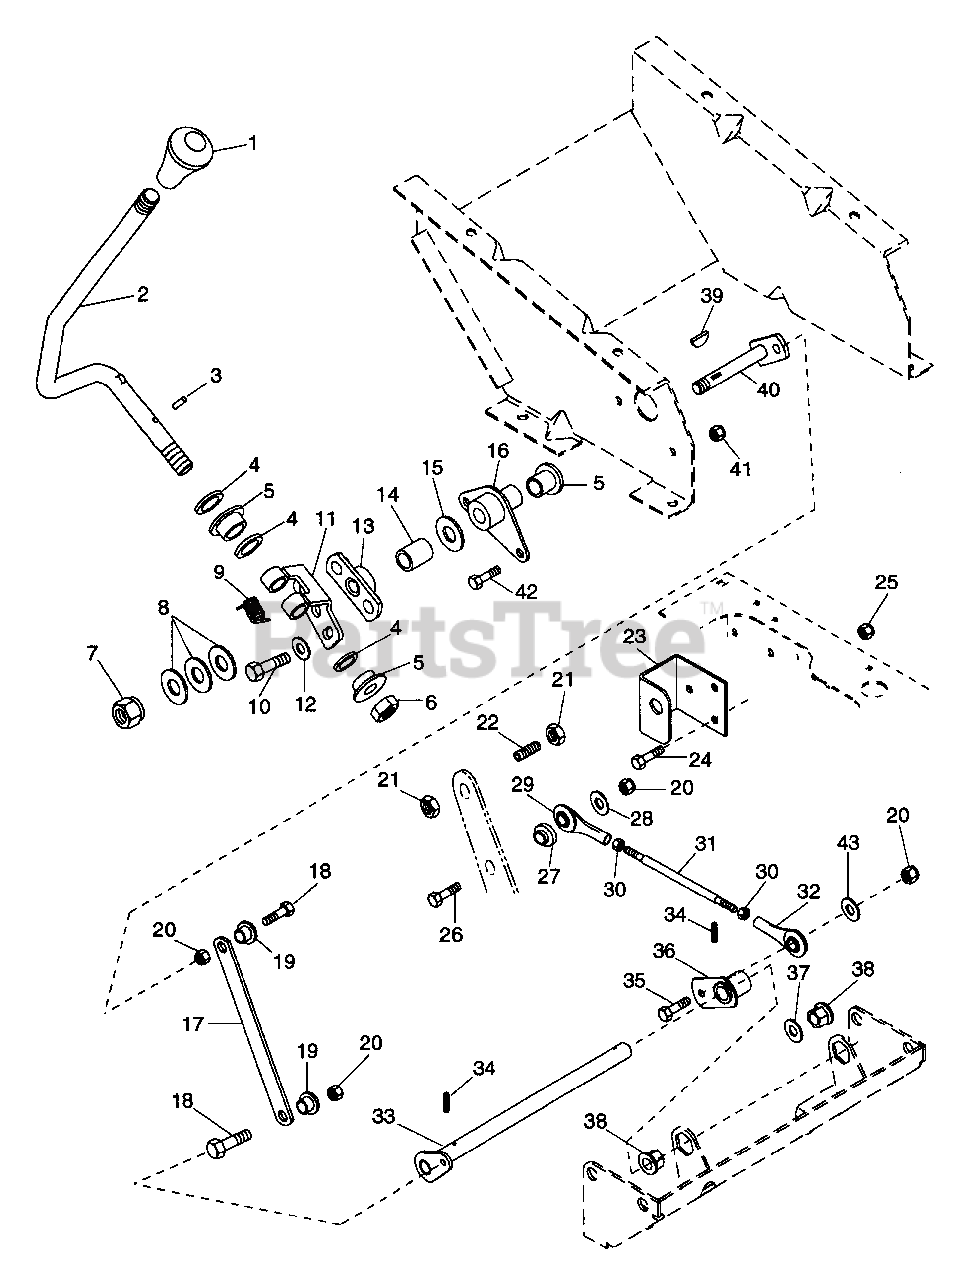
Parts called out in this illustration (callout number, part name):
2	SHIFT LEVER
3	PIN-ROLL .125X1.00
4	WSHR-FL-STL .520X.827X.062 YZ
5	BSHG-FLG .500X.625X.625X.875
6	NUT-LK-NYL .50-13 GR 5 PL
7	NUT-LK-CTR .50-20 PL
8	SPRING WASHER
9	SG_TORS .08X.56X.65
10	BLT-HEX .38-16X1.00 PL GR5
11	OUTER ARM
12	WSHR-FL-STL .382X.812X.062
14	BSHG-SLV .500X.625X.500
15	FRICTION WASHER
16	SHEAVE EXTENSION SHAFT
17	SHIFT LINK
18	BLT-HEX .25-20X.63 PL GR2
19	BSHG-FLG .265X.437X.250X.750
20	NUT-LK-CTR .250-20 PL
21	NUT-JAM .375-16 PL
22	SCR-SET .38-16X1.00 SKHCUP
23	SWITCH BRACKET
24	BLT-HEX .25-20X.75 PL GR2
25	NUT-LK-NYL .250-20 PL
26	BLT-HEX .25-20X1.25 PL GR5
27	BSHG-FLG .254X.371X.380X.500
28	WSHR-FL-STL .250X.562X.049 PL
29	ROD END, 1/4 RH
30	NUT-HEX .250-28 YWZC
31	SHIFT ROD
32	ROD END, 1/4 LH
33	CROSS SHAFT
34	PIN-ROLL .125X.88
35	BLT-HEX .25-20X1.00 GR2
36	ARM & HUB
37	WSHR-FL-STL .630X1.005X.062 PL
38	BSHG-FLG .625X.875X.750X1.19HX
39	KEY-WDRF .125X.500X.203 SAE 3
41	NUT-LK .312-18 GR A PL
42	BLT-HEX .31-18X.63 PL GR 2
43	WSHR-FL-STL.281X.62X.065 PL
